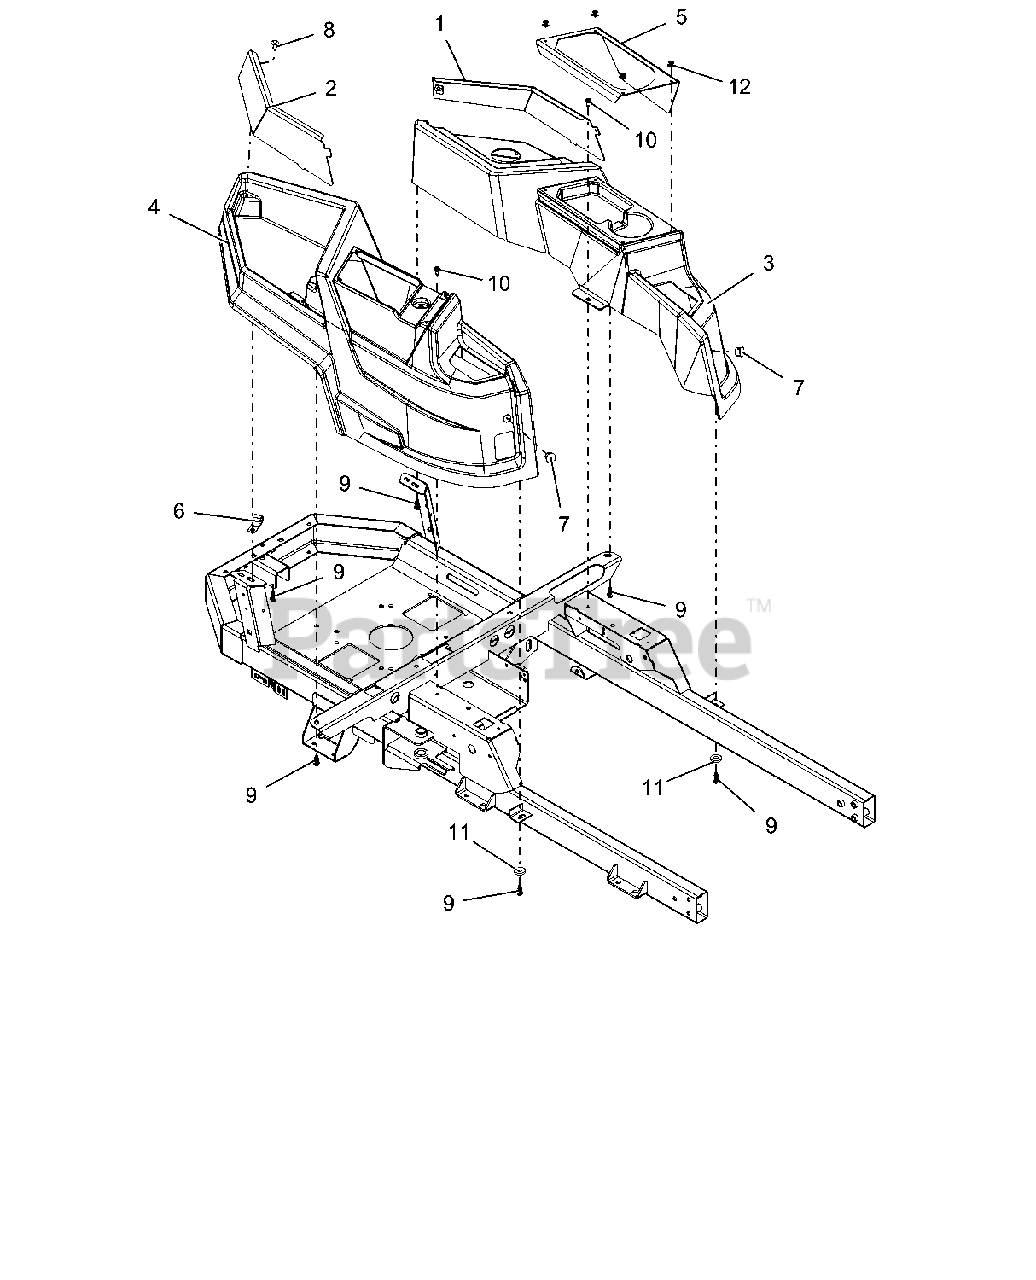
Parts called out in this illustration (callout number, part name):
1	WLDMT, FENDER BLOCKOFF XL -LH
2	WLDMT, FENDER BLOCKOFF-RH XL
3	FENDER, LH -ZOOM
4	FENDER, RH -ZOOM
5	PANEL, CUPHOLDER/STORAGE (LH)
6	J-CLAMP
7	PLUG, HOLE .75 (BLACK)
8	XMAS TREE FASTNER-BLACK
9	SCR-.312X.75 #14H H/W/H H/L CZ
10	SCR-TAP .25-20X.50 HWH TR YWZ
11	WSHR-FL-STL .406X1.00X.188 YWZ
12	RIVET, PLASTIC .195 DIA.
